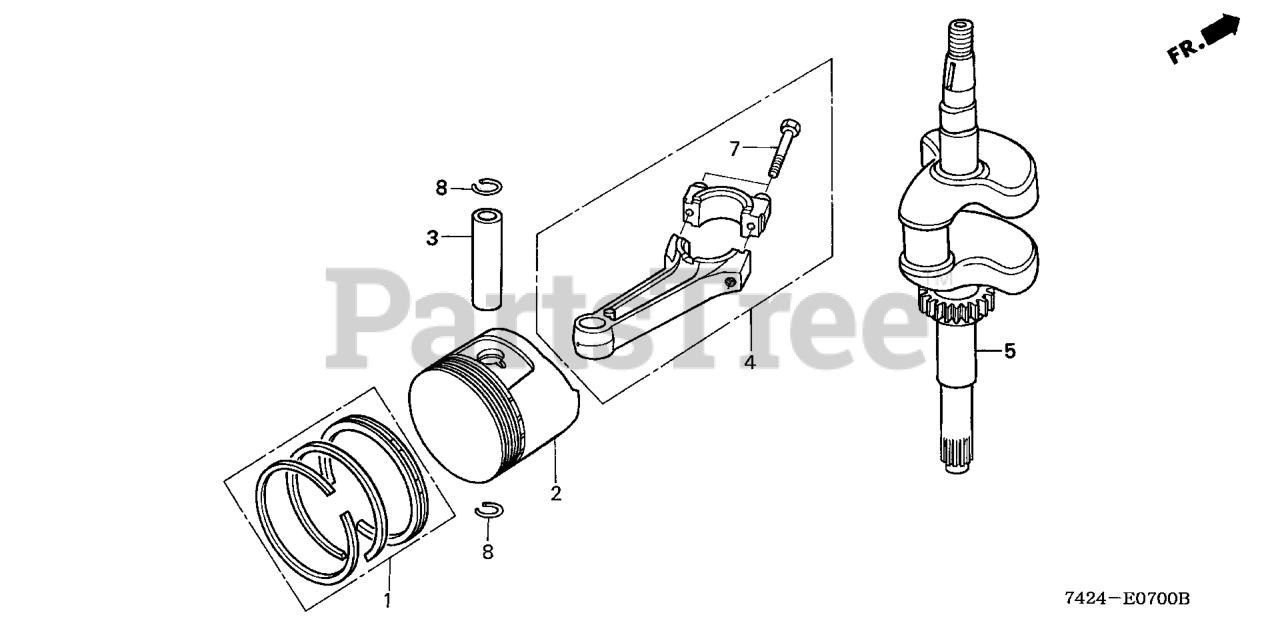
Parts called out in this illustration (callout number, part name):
1	RING SET, PISTON (STD) (NIPPON)
1	RING SET, PISTON (OS 0.25) (Honda Code 7066418). (NIPPON)
1	RING SET, PISTON (OS 0.50) (Honda Code 7066426). (TEIKOKU)
1	RING SET, PISTON (OS 0.50) (Honda Code 7066434). (NIPPON)
1	RING SET, PISTON (0.75) (Honda Code 7066459). (NIPPON)
2	PISTON (STD)
2	PISTON (0.25) Use from Engine SN 2554751.
2	PISTON (0.50) Use from Engine SN 2554751.
2	PISTON (0.75) Use from Engine SN 2554751.
3	PIN, PISTON
4	ROD ASSY., CONNECTING
4	ROD ASSY., CONNECTING (US 0.25) Use from Engine SN 2250473.
5	CRANKSHAFT
7	BOLT, CONNECTING ROD
8	CLIP, PISTON PIN (13MM)
